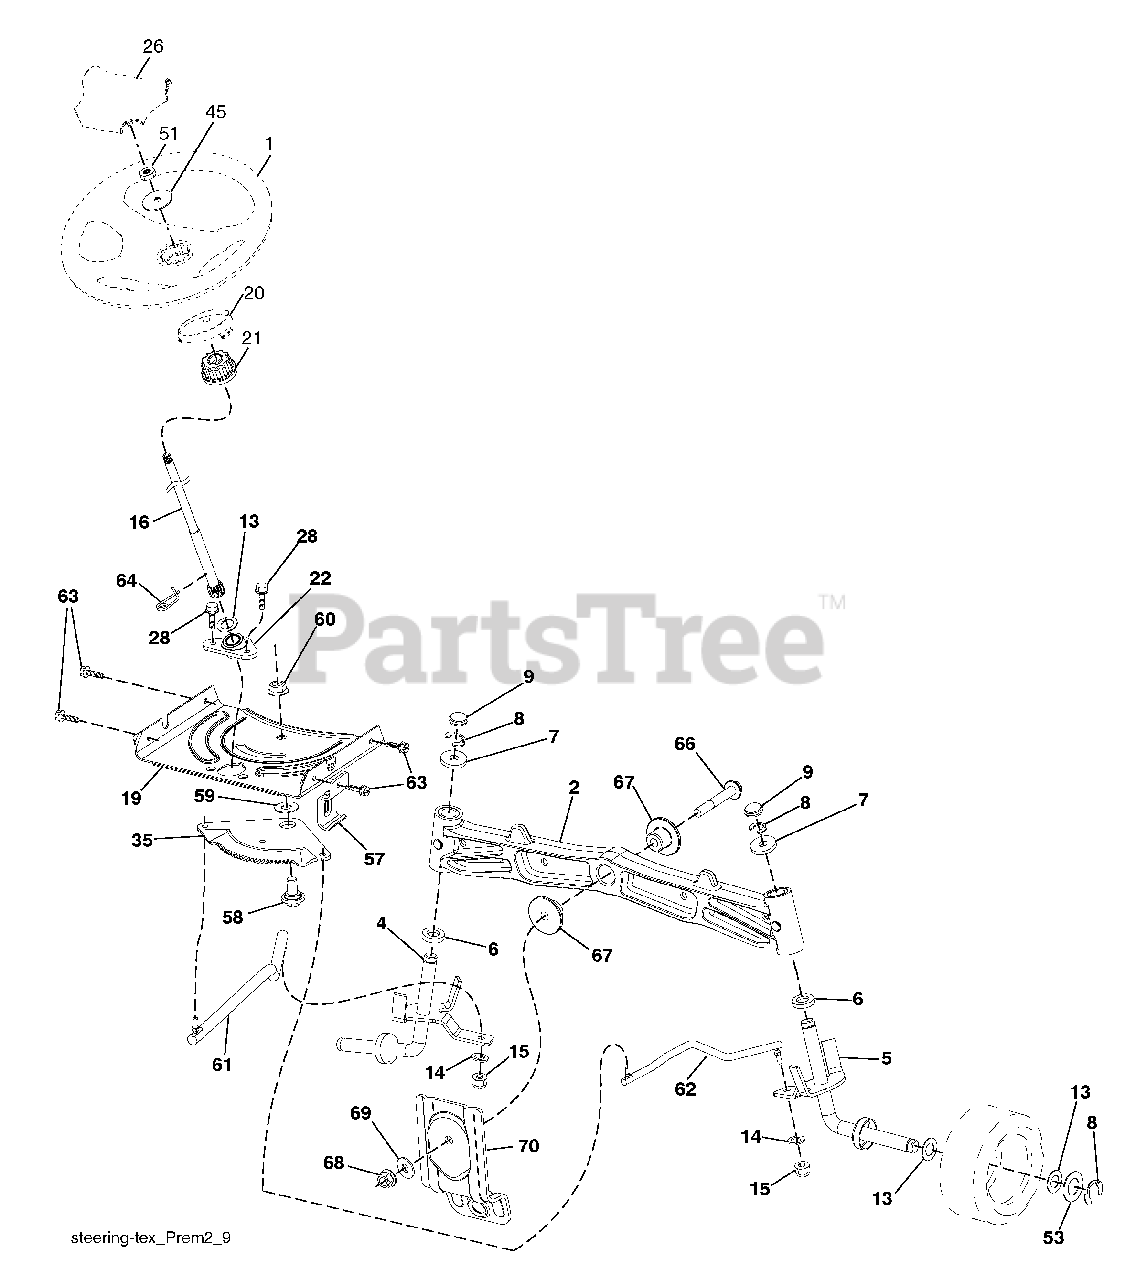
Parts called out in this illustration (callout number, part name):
1	Wheel, Steering
2	Axle Asm., Front
4	Spindle Asm., LH
5	Spindle Asm., RH
6	Bearing, Race Thrust Harden
7	Washer 25/32 x 1-5/8 x 16 Ga.
8	Ring, Klip #T5304-75
9	Cap, Spindle
13	Washer 25/32 x 1-1/4 x 16 Ga.
14	Washer, Lock Hvy Hlcl Spr 3/8
15	Nut, Crown Lock 3/8-24 unf
16	Shaft Steering
19	Plate Steering
20	Boot, Steering
21	Adapter, Wheel Steering
22	Strg. Supt. Lower
26	Insert, Wheel Steering
28	Screw 3/8-16 x 3/4
35	Gear, Sector Plate
45	Washer 9/16 x 2-3/8 x 12 Ga.
51	Nut Hex Jam Toplock 1/2-20 unf
53	Washer Hardened .793 x 1.637 x .060
57	Bracket Upstop
58	Bolt Shoulder Sector Pivot CFM
59	Washer Thrust Sector Steering
60	Nut Flange Lock 5/8-11
61	Draglink LH
62	Draglink, RH
63	Screw 5/16-18 x 3/4
64	Retainer Clip Spring Steering
66	Bolt Hex Fghd 7/16-14 x 3 Serr
67	Bushing PM Front Axle
68	Nut Lock Flange 7/16-14 Gr. 5
69	Washer 1.5 x .505 x .118
70	Bracket Deck Susp. Front
